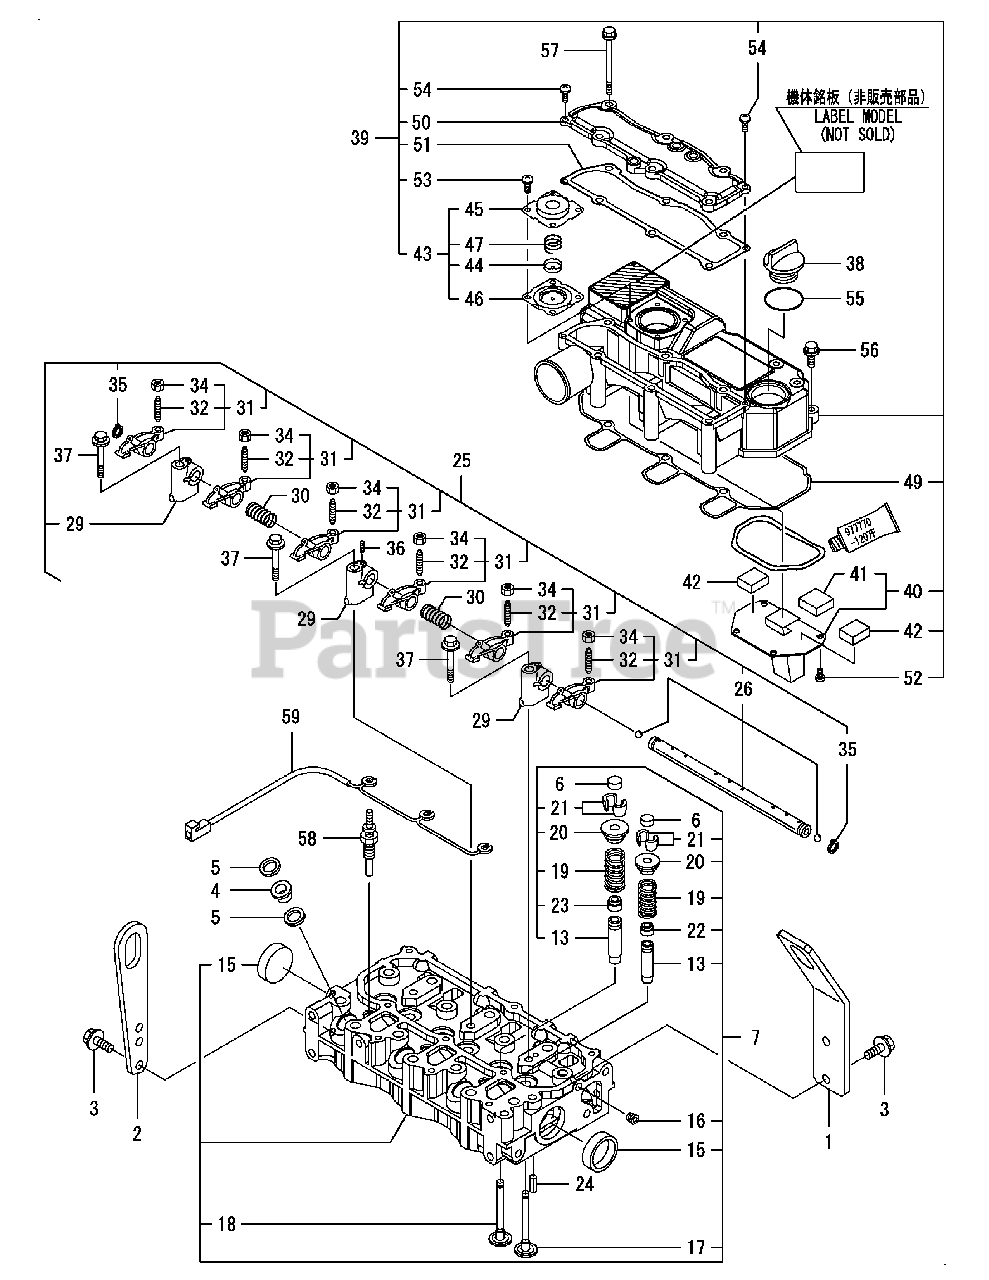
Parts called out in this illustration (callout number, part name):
1	LIFTER, ENGINE
2	LIFTER, ENGINE
3	BOLT M 8X 16 PLATED
4	PROTECTER, NOZZLE
5	GASKET, NOZZLE
7	HEAD ASSY, CYLINDER
15	PLUG 35
16	PLUG PT 1/16,SCREW
18	VALVE, EXHAUST
20	RETAINER, SPRING
22	SEAL, VALVE STEM
23	SEAL, VALVE STEM
24	SPRING PIN 6X12
25	SUPPORT ASSY, ARM
26	SHAFT ASSY, ROCKER
29	SUPPORT, ROCKER ARM
31	ARM ASSY, ROCKER
37	BOLT M 8X 40 PLATED
39	BONNET ASSY, HEAD
41	BAFFLE, BREATHER
42	BAFFLE, BREATHER
43	DIAPHRAGM ASSY
44	PLATE, DIAPHRAGM
45	COVER, DIAPHRAGM
47	SPRING, DIAPHRAGM
49	GASKET, BONNET
51	GASKET BONNET COVER
52	SCREW 5X10,TAPPING
53	SCREW 5X10,TAPPING
55	O-RING 1A P-32.0
56	BOLT M 6X 20 PLATED
57	BOLT M 6X 75 PLATED
59	CONNECTOR, GLOW PLUG
